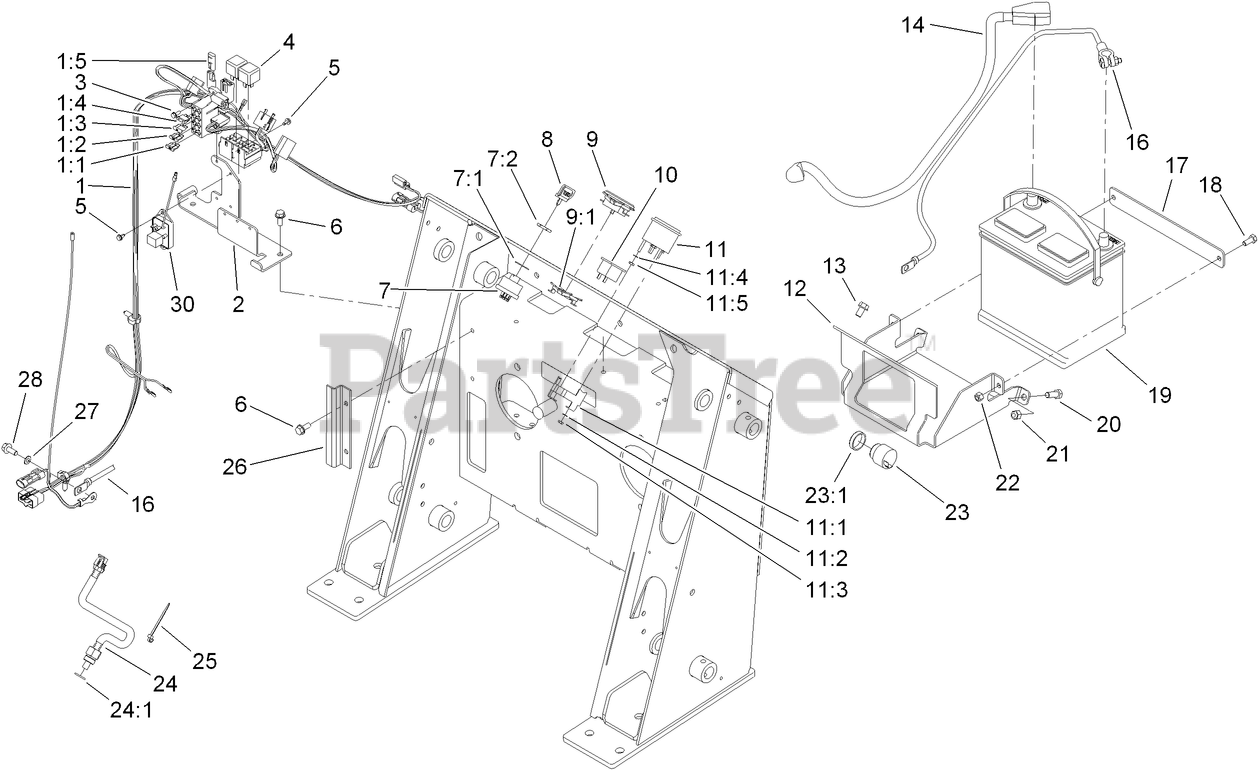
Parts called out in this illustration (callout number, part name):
1	HARNESS-WIRE
1:1	FUSE-BLADE, 30 AMP
1:2	FUSE-BLADE, 25 AMP
1:3	FUSE-BLADE, 10 AMP
1:4	FUSE-BLADE, 15 AMP
1:5	CAP-PLUG
2	BRACKET-FUSE/RELAY
3	SCREW-HWH
4	RELAY
5	SCREW-HWH
6	SCREW-HWHTF
7	Key Switch ASM
7:1	WASHER-TOOTH, INTERNAL
7:2	NUT-HH
8	KEY-IGNITION
9	INDUCTIVE HOURMETER ASM
9:1	CLIP-MOUNTING
10	LIGHT-TEMP, OIL
11	GAUGE-FUEL
11:1	BRACKET-MOUNTING, GAUGE
11:2	WASHER-LOCK, INT
11:3	NUT-HEX
11:4	WASHER-LOCK / EXT
11:5	NUT-HEX
12	TRAY-MOUNTING, BATTERY
13	SCREW-HWHTF
14	CABLE-BATTERY, POSITIVE
16	CABLE-BATTERY, NEGATIVE
17	CLAMP-BATTERY
18	SCREW-HH
19	BATTERY
20	SCREW-HH
21	NUT-LOCK, NI
22	NUT-LOCK, NI
23	AUDIO ALARM ASM
23:1	NUT-PLASTIC, KNURLED
24	SENSOR-TEMPERATURE
24:1	O-RING
25	TIE-CABLE
26	SHIELD-WIRING
27	WASHER-LOCK
28	SCREW-HHF
30	MODULE-IGNITION DELAY
